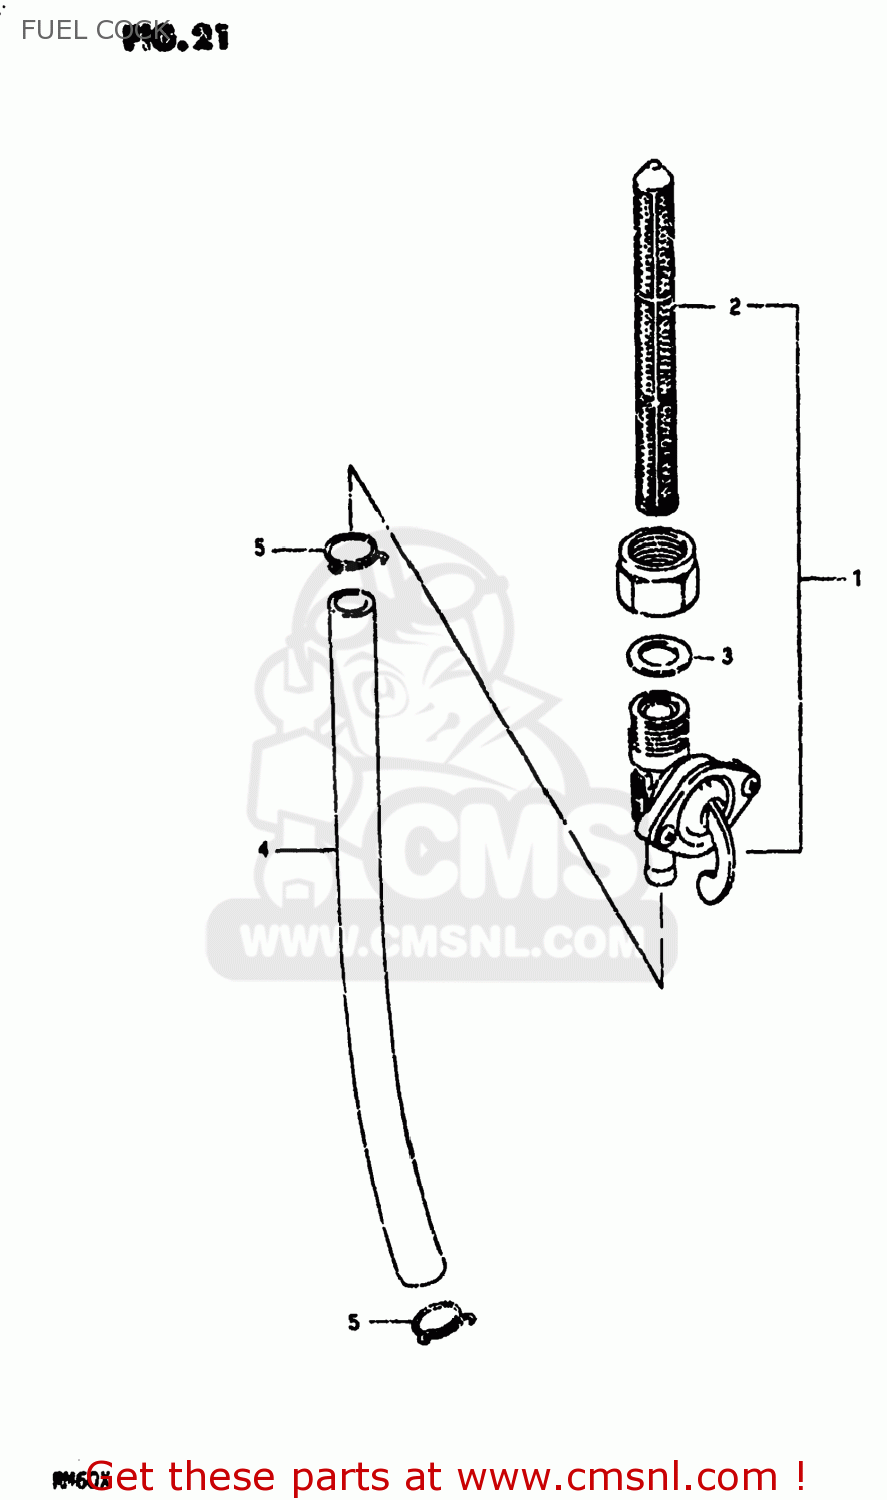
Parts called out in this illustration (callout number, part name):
1	COCK ASSY,FUEL
2	FILTER,FUEL
3	GASKET,FUEL COCK (NAS)
4	HOSE
5	CLIP
